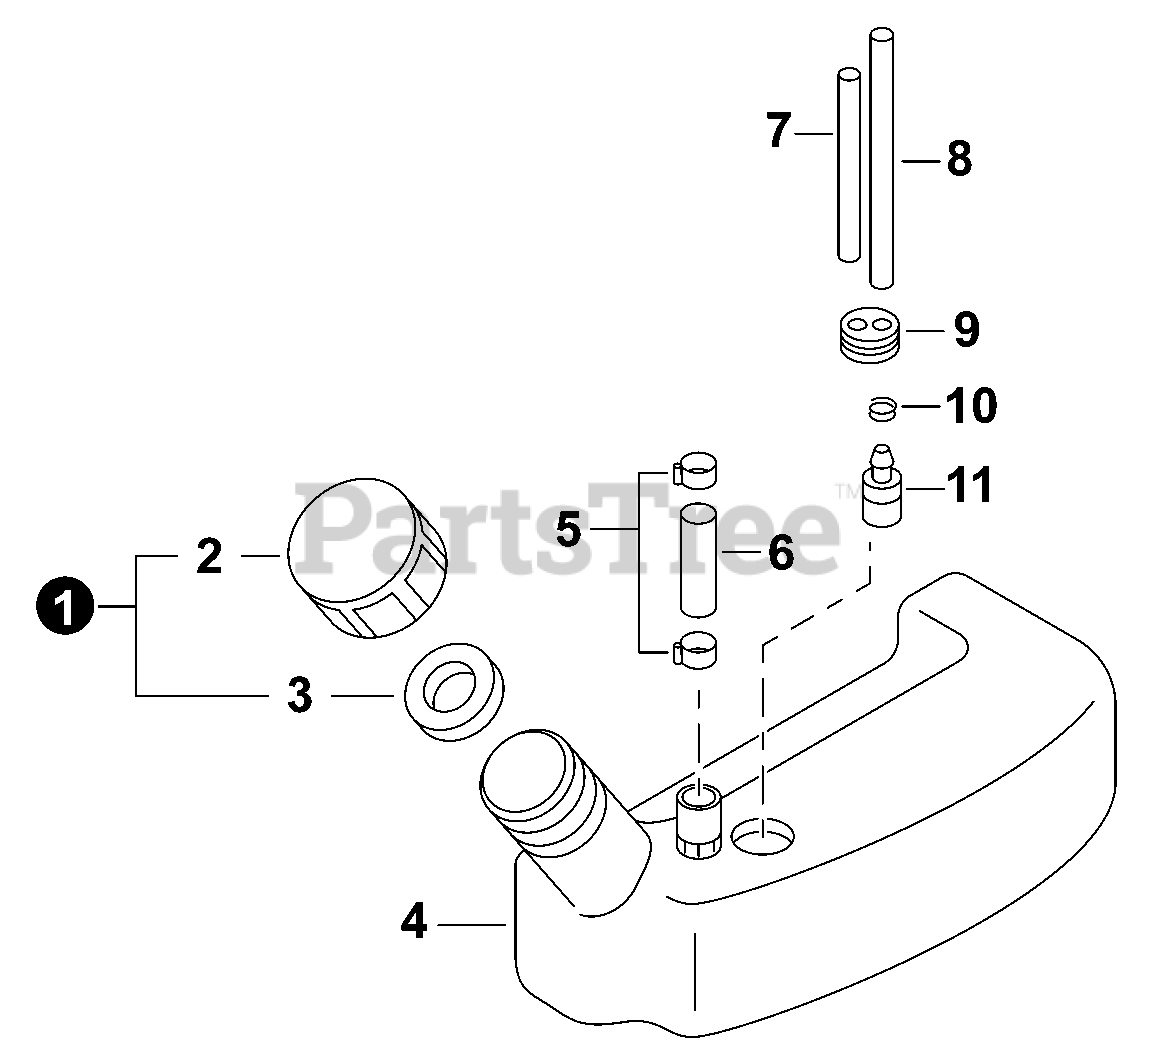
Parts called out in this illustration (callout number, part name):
1	CAP ASSY, FUEL
2	CAP, FUEL TANK
3	GASKET, FUEL CAP
4	TANK, FUEL
5	CLIP 10.5 MM
6	PIPE, FUEL 8x11x70
7	PIPE, FUEL
8	PIPE, FUEL 3x6x200
9	GROMMET, FUEL
10	CLIP 6.5 MM
11	FILTER, FUEL
